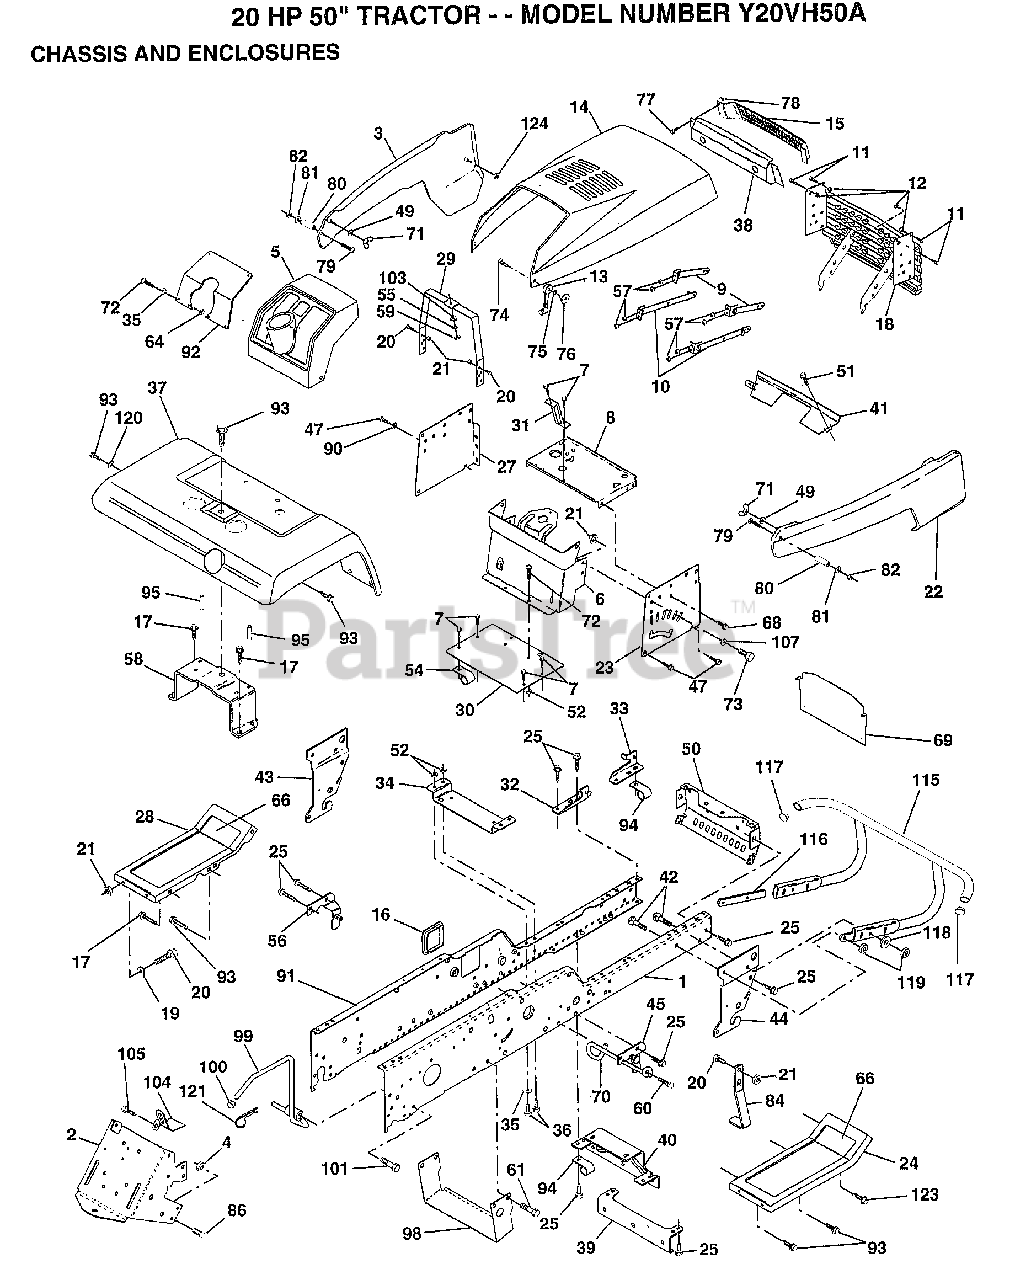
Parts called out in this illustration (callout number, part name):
2	DRAWBAR GT
4	NUT.7/16
5	DASHBOARD BLACK
6	DASH ASM LOWER
7	SCREW
8	SUPPORT BATRY VGT
12	NUT
13	HOOD LATCH T
15	LENS LT
16	COVER ACCESS
17	SCREW
18	GRILLE.ASM.PNT.YP
19	WASHER
20	BOLT
21	NUT
22	PANEL SIDE RH
25	SCREW
29	SUPPORT ASS'Y
30	SADDLE SLKSCRNED
31	BRACE.SUPT.STRG
32	BRACKET ASM FRAME
33	BRACKET ASM FRAME
34	BRACKET.ENG.SUPT.
35	WASHER
36	BOLT
37	FENDER.PNT.
39	BRACKET.AXLE.FRT.
41	STRAP.GRILLE.PNT.
42	BOLT.3/8-14X1.25
43	BRACKET.SUS.FT.LH
44	BRACKET.SUS.FT.RH
47	SCREW LT
49	WASHER
50	BRACKET.CHASSIS.
51	SCREW CRT
52	NUT
54	"CLIP,INSULATOR"
55	WASHER PM
57	NUT
58	BRKT.ASM.FENDER
60	SCREW
61	SCREW
62	RETAINER M
66	FOOTREST PAD
68	SCREW LT
69	SHIELD.HEAT.VGT.
70	GUIDE.BELT.MID.SP
72	SCREW
73	BOLT
74	SCREW
75	LOCKWASHER
76	WELDNUT
78	"""J"" FASTENER LT"
79	SCREW
80	SPACER LT
81	WASHER
84	STOP.OVER.CENTER
86	BOLT
90	LOCKWASHER
92	PLATE DASH SILKSC
93	SCREW LT
94	CLIP GTV
95	NUT-PUSH YT
96	PLUG-DASH T
98	BRACKET SKID CHAS
99	ROD BYPASS
101	SCREW LT
103	LOCKWASHER
104	LOCK BYPASS BRKT
105	SCREW LT
115	BUMPER.ASM.W/PY
116	BRACKET.EXT.BUMP.
117	PLUG.PLASTIC
118	WASHER
120	WASHER HYT
123	SCREW GTV
124	PAL NUT LT
